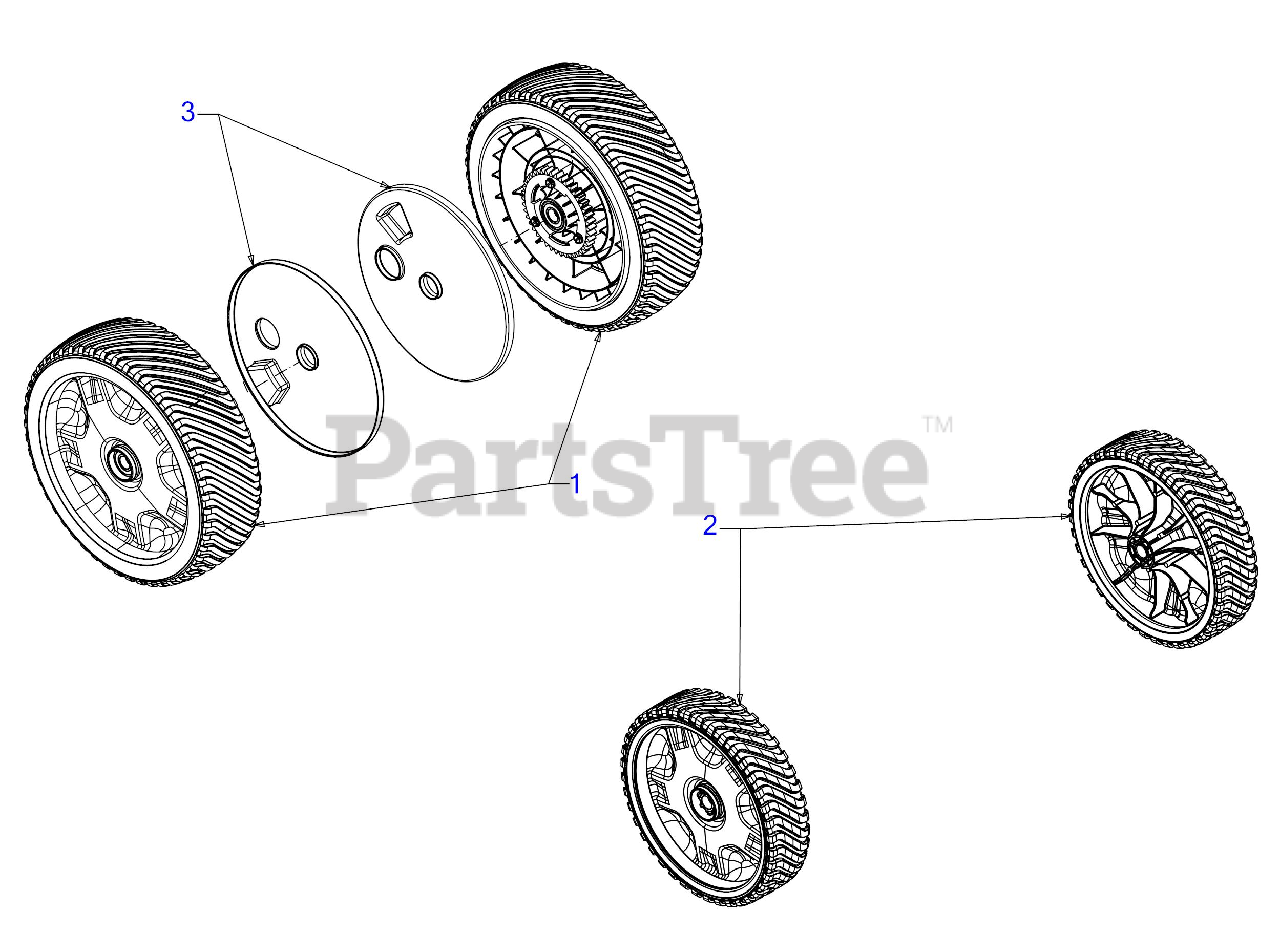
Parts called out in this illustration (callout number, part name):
1	DRIVE WHEEL ASSEMBLY 10 X 3 GRAY
2	WHEEL ASM-8X2 (OYSTER GRAY)
3	DUST COVER 10"
